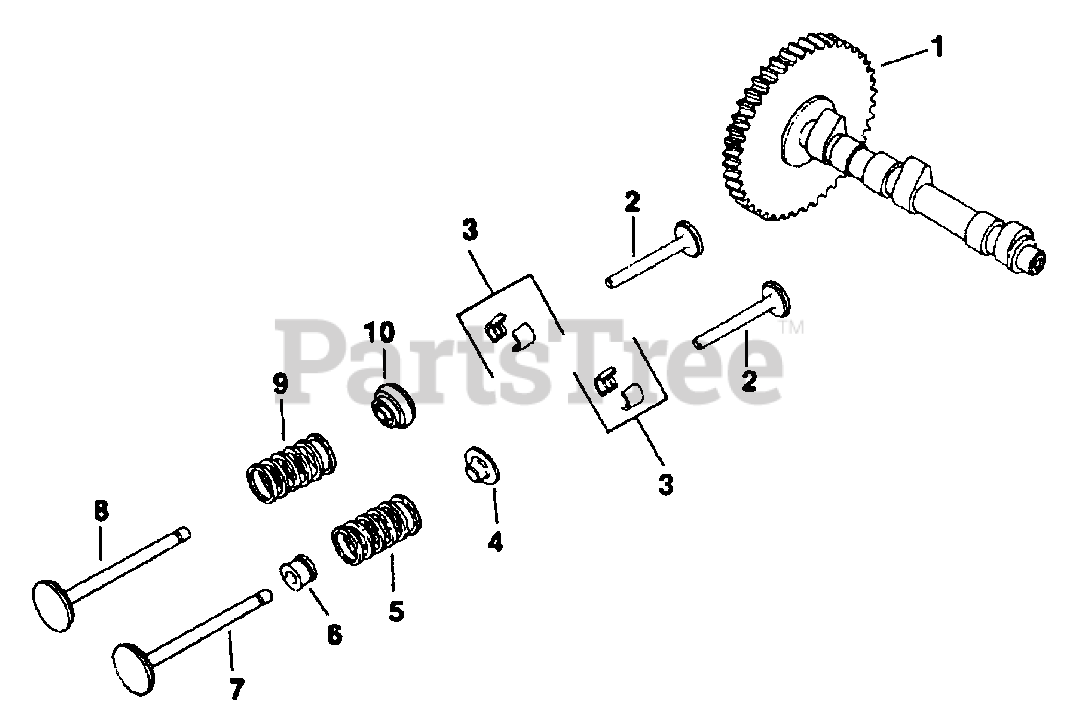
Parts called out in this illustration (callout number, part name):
1	CAMSHAFT
2	TAPPET
3	KIT, RETAINER
4	RETAINER, INTAKE VALVE
5	SPRING
6	SEAL
7	VALVE
8	VALVE
9	SPRING
10	ROTATOR
